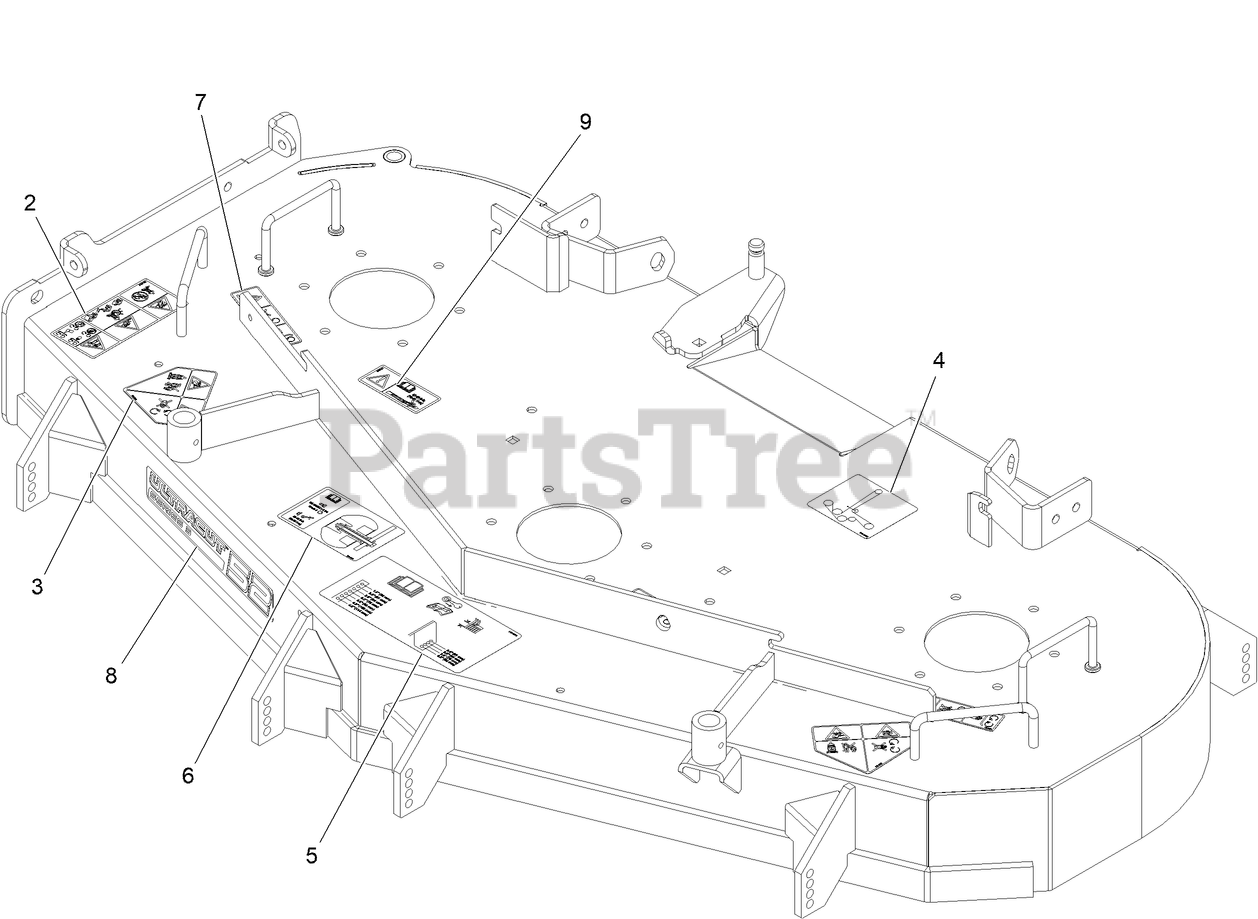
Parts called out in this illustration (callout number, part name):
2	DECAL-WARNING THROWN OBJ
3	DECAL-DANGER
4	DECAL-BELT ROUTING
5	DECAL-ANTI-SCALP
6	DECAL-ROLLER MOUNTING
7	DECAL-COVER, MISSING
8	DECAL-ULTRACUT 52 SERIES 3
9	DECAL-TORQUE, BOLT
